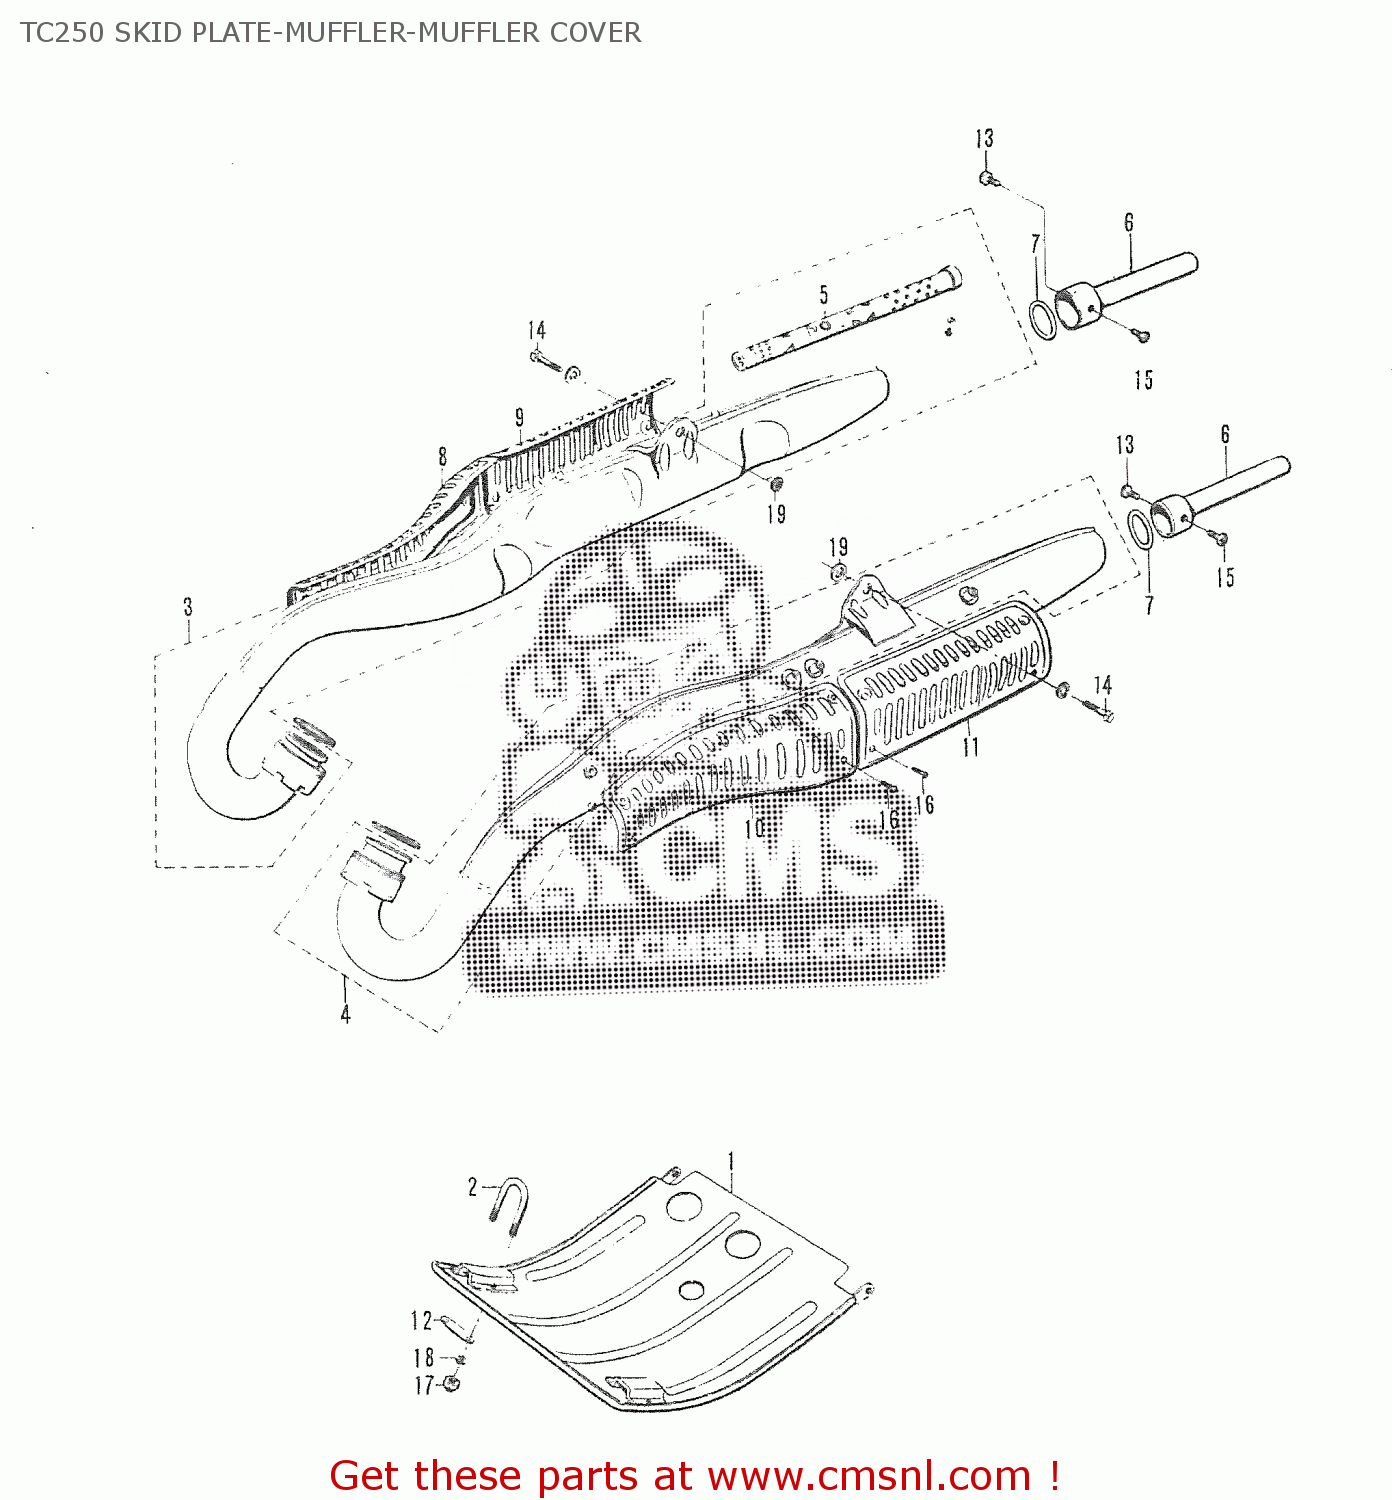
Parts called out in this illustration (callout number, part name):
1	SKID PLATE
2	BRACKET,ENGINE PROTECT
3	RIGHT MUFFLER ASS'Y
4	LEFT MUFFLER ASS'Y
5	MUFFLER BAFFLE PIPE
6	MUFFLER TAIL PIPE
7	MUFFLER TAIL PIPE GASKET
8	RIGHT MUFFLER FRONT COVER
9	RIGHT MUFFLER REAR COVER
10	LEFT MUFFLER FRONT COVER
11	LEFT MUFFLER REAR COVER
12	WASHER
13	HEXAGON BOLT
14	CROWN HEAD BOLT
15	CROSS HEAD SCREW
16	CROSS HEAD SCREW
17	CROWN NUT
18	LOCK WASHER
19	FLAT WASHER
